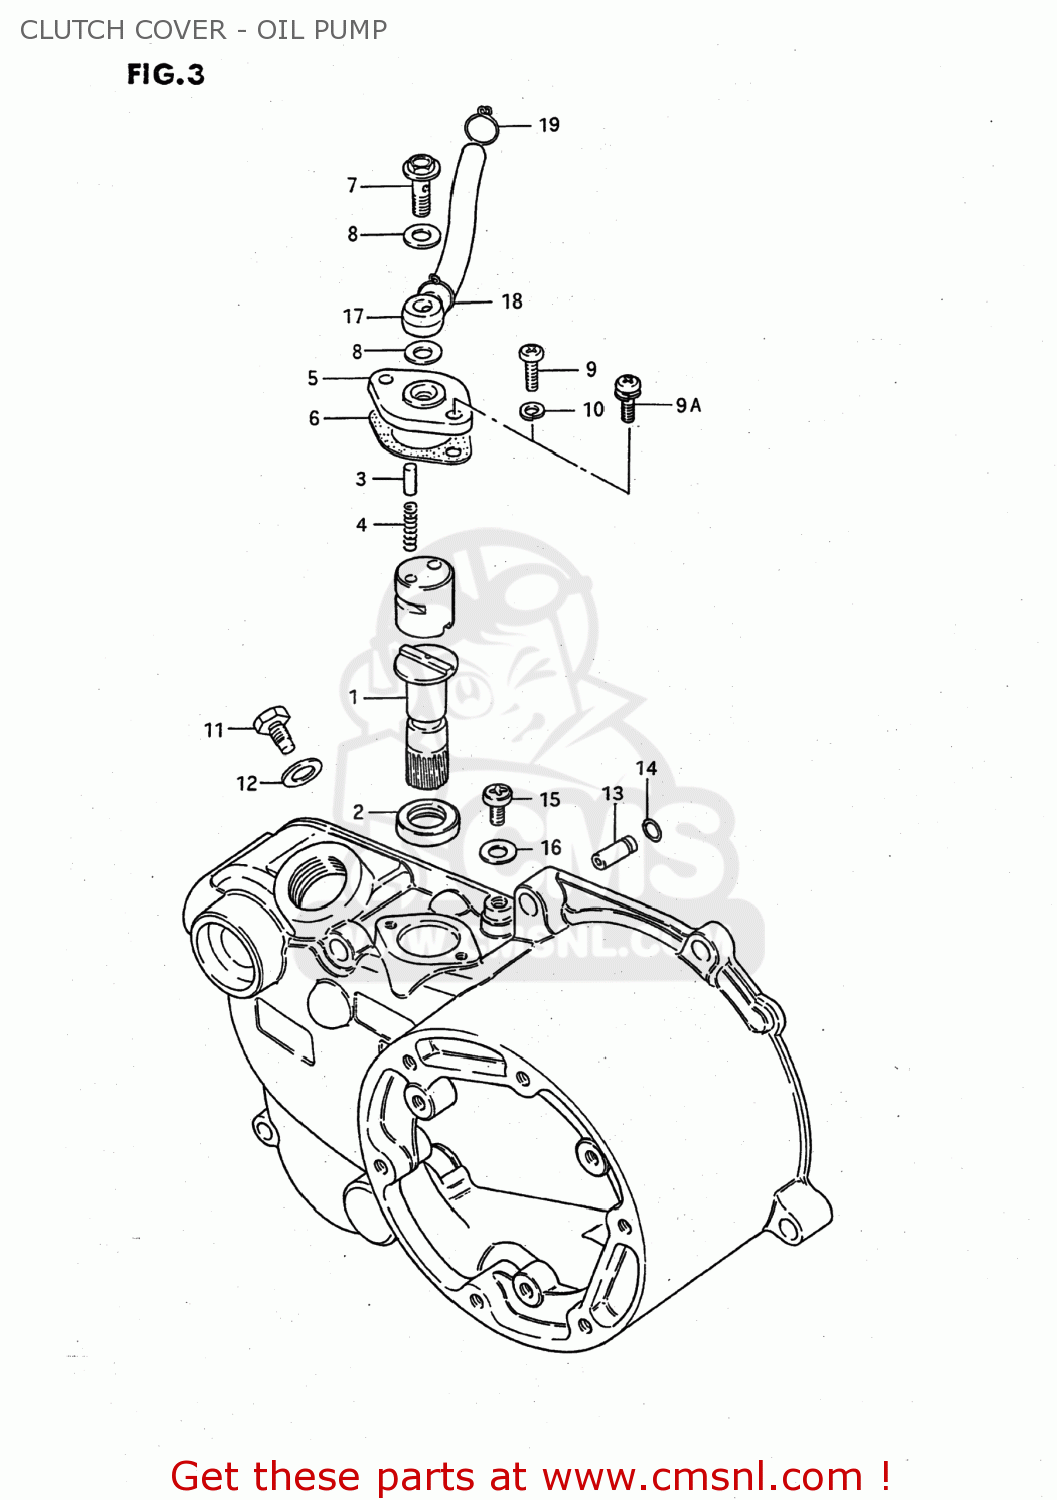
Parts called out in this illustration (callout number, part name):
1	GEAR,OIL PUMP DRIVE
2	SEAL,OIL(12X18.5X3)
3	PIN(2.3X7.5)
4	SPRING
5	CAM,OIL PUMP
6	GASKET,OIL PUMP (NAS)
7	UNION BOLT
8	GASKET(6.2X11X1).2 (NAS)
9	SCREW
9A	SCREW
10	WASHER,LOCK 4M
11	BOLT(6X10)
12	WASHER
13	VALVE,CRANK CHECK
14	O RING(D:1.05,ID:3.1)
15	SCREW
16	GASKET(5X9.5X1) (NAS)
17	HOSE,INLET
18	CLIP
19	CLIP
